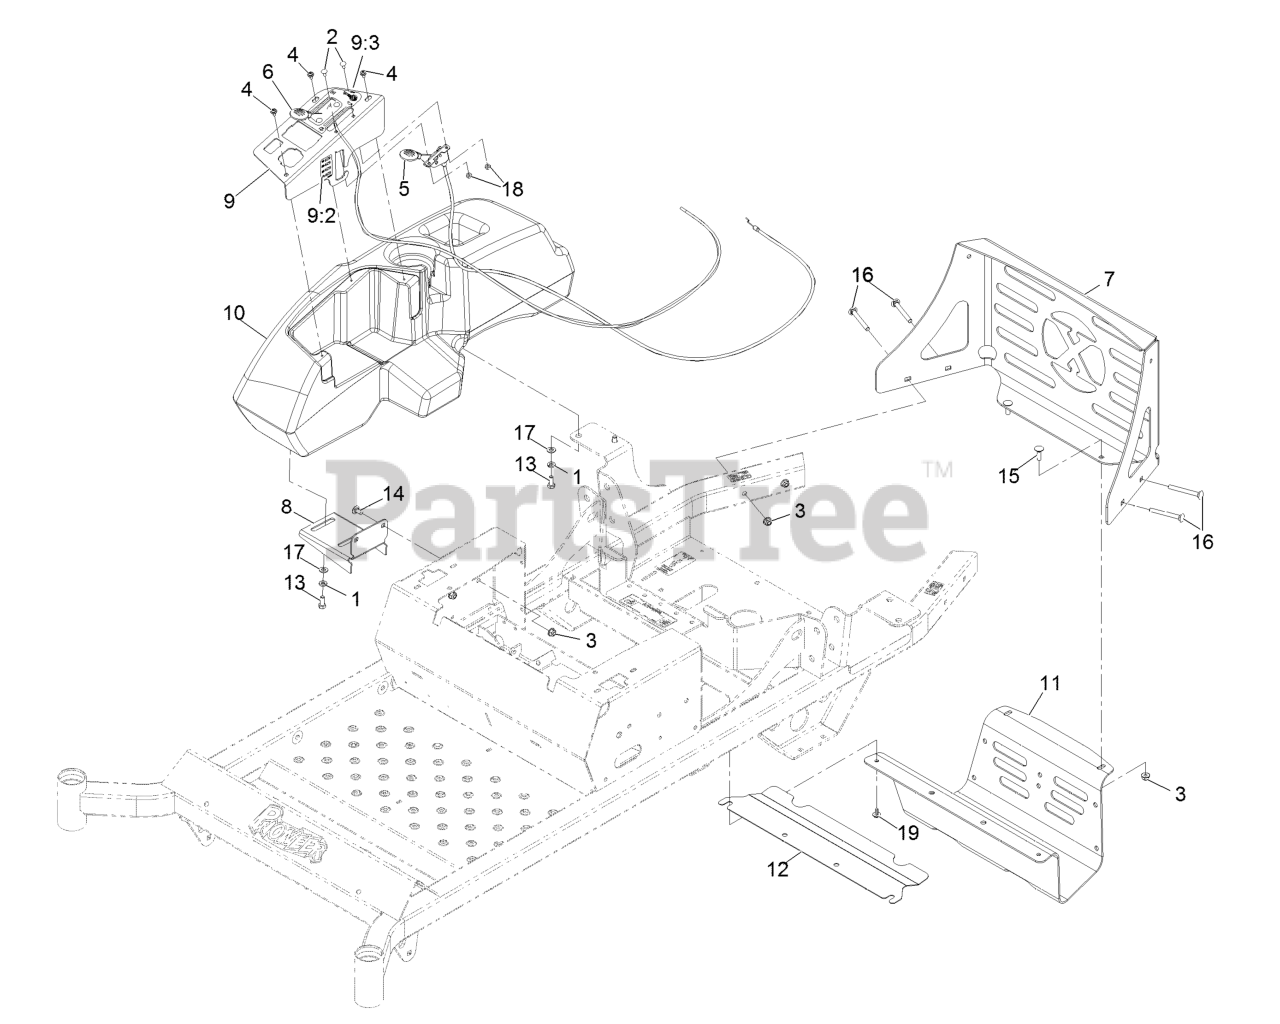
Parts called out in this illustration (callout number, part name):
1	WASHER-LOCK
2	BOLT-CARR
3	NUT-HF, NI
4	SCREW-PPH
5	CONTROL-THROTTLE
6	CONTROL-CHOKE
7	PANEL,REAR GUARD
8	BRACKET-TANK AND FENDER
9	ASM, CONTROL PANEL W/ DEC
9:2	DECAL,FUSE BLOCK
9:3	DECAL-THROTTLE CHOKE
10	CONSOLE,RH
11	GUARD-MUFFLER
12	SHIELD, HEAT
13	SCREW-HH
14	SCREW-CARR
15	BOLT-CARR
16	SCREW-CARR
17	WASHER-PLAIN
18	NUT-LOCK, NI
19	SCREW-HHFTF
